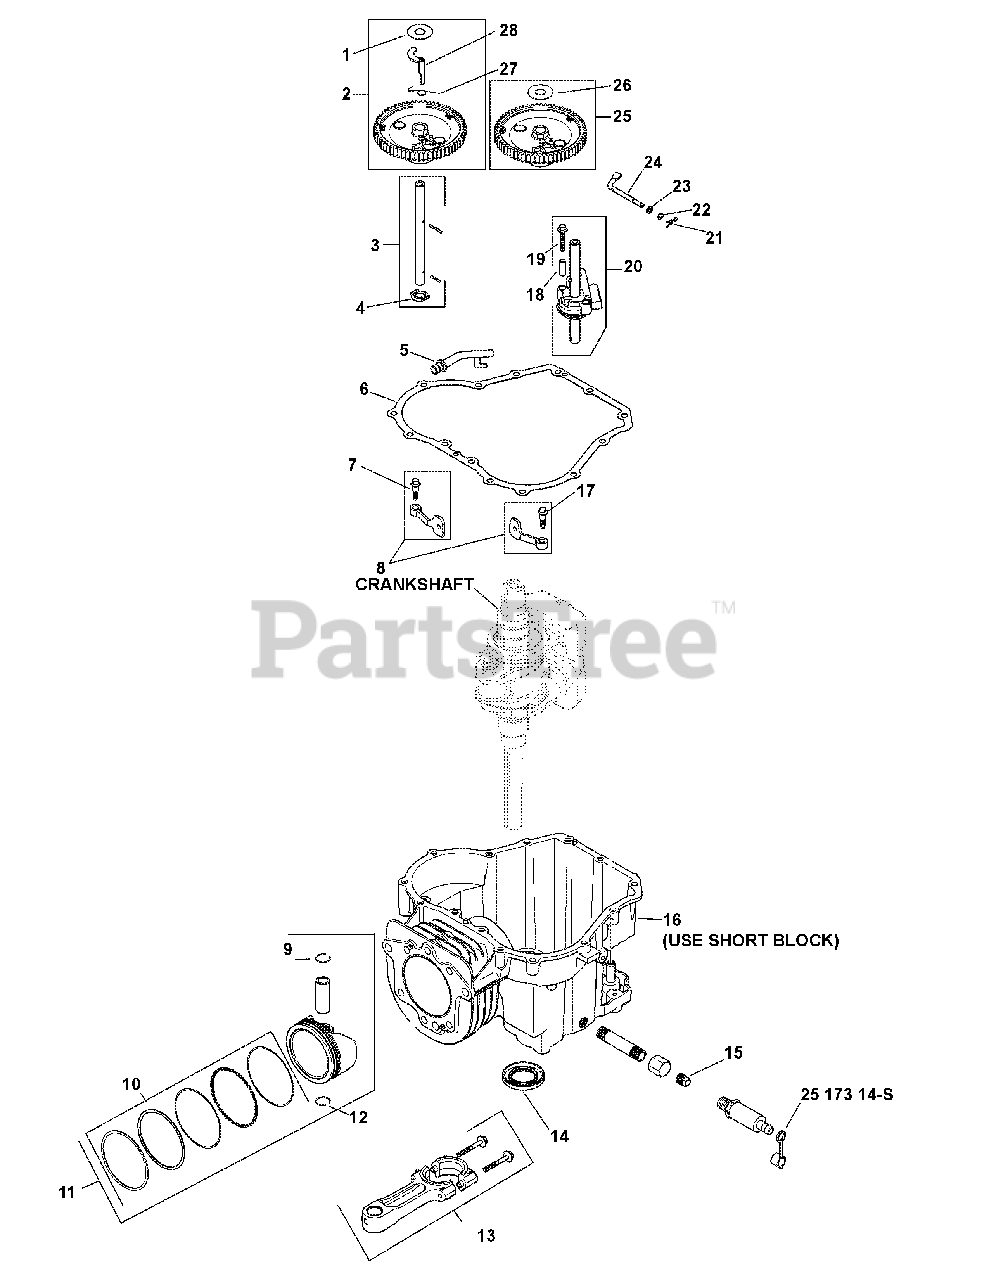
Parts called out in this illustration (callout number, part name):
1	Washer, Thrust -Acr
2	Kit, Camshaft Assembly
3	Kit,Cam Center Shaft (Exhaust)
4	Washer, Thrust
5	Tube, Drainback
6	Gasket, Closure Plate
7	Screw, Shd Thd Frm M6X1X26
8	Kit, Cam Lever Assembly
9	Retainer, Piston Pin
10	Ring Set (94Mm)
11	Kit, Piston W/Ring Set (94Mm)
12	Retainer, Piston Pin
13	Rod, Connecting Assembly
14	Seal, Oil
15	Plug, Sq Hd Pipe 3/8"
16	Crankcase
17	Screw, Shd Thd Frm M6X1X26
18	Spacer, Oil Pump Screw
19	Screw, Oil Pump
20	Kit, Oil Pump Assembly
21	Clip, Hitch Pin
22	Washer, Flat 1/4"
23	Washer, Flat 6 Mm
24	Shaft, Governor Cross
25	Kit, Camshaft Assembly
26	Washer, Thrust -ACR
28	Weight, ACR
